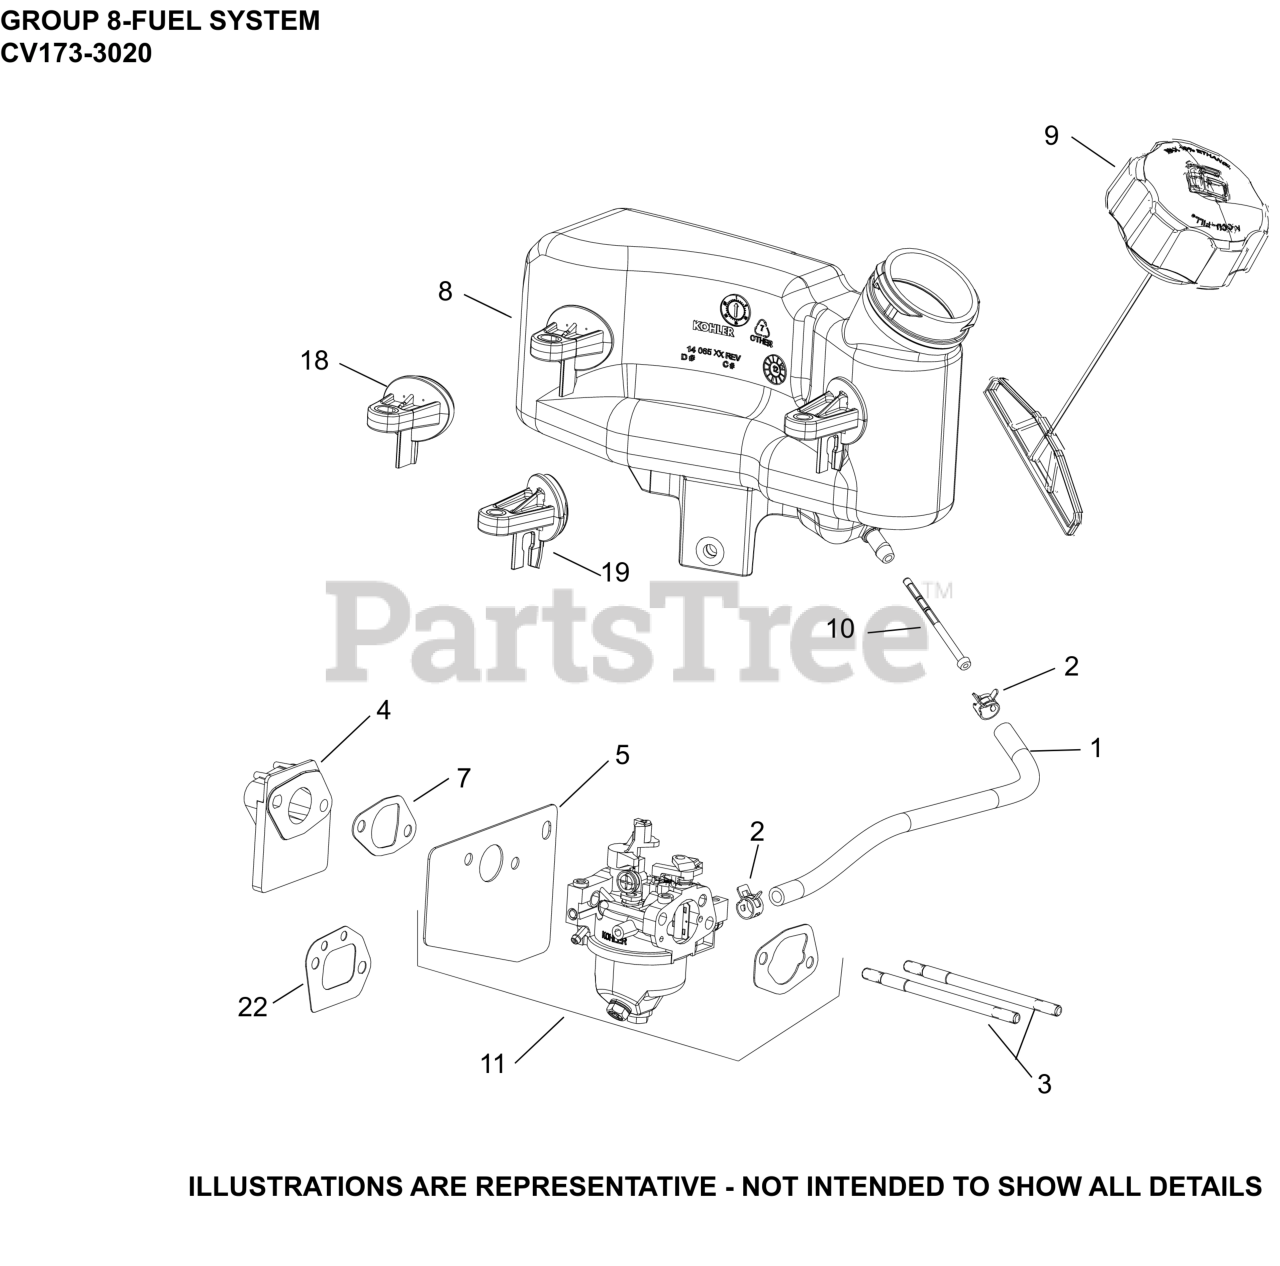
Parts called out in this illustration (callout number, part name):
1	HOSE, FUEL LOW-PERMEATION
2	CLAMP, HOSE (NON-CALIF)(#1423710S)
3	STUD,M6X1.0X100.2MM
4	KIT, SPACER
5	KIT, CARBURETOR HEAT SHIELD GASKET
7	KIT, INTAKE GASKET
8	TANK, FUEL
9	FUEL CAP ASSEMBLY
10	FILTER, FUEL IN-NIPPLE
11	KIT, CARBURETOR COMPLETE
18	BRACKET, FUEL TANK-DISCONTINUED
19	BRACKET, FUEL TANK-DISCONTINUED
22	GASKET SPACER
NI	KIT, HIGH ALT (4000-8000 FT)
NI	KIT, HIGH ALT (8,000+ FT)
NI	KIT, CARBURETOR REPAIR (RUIXING)
